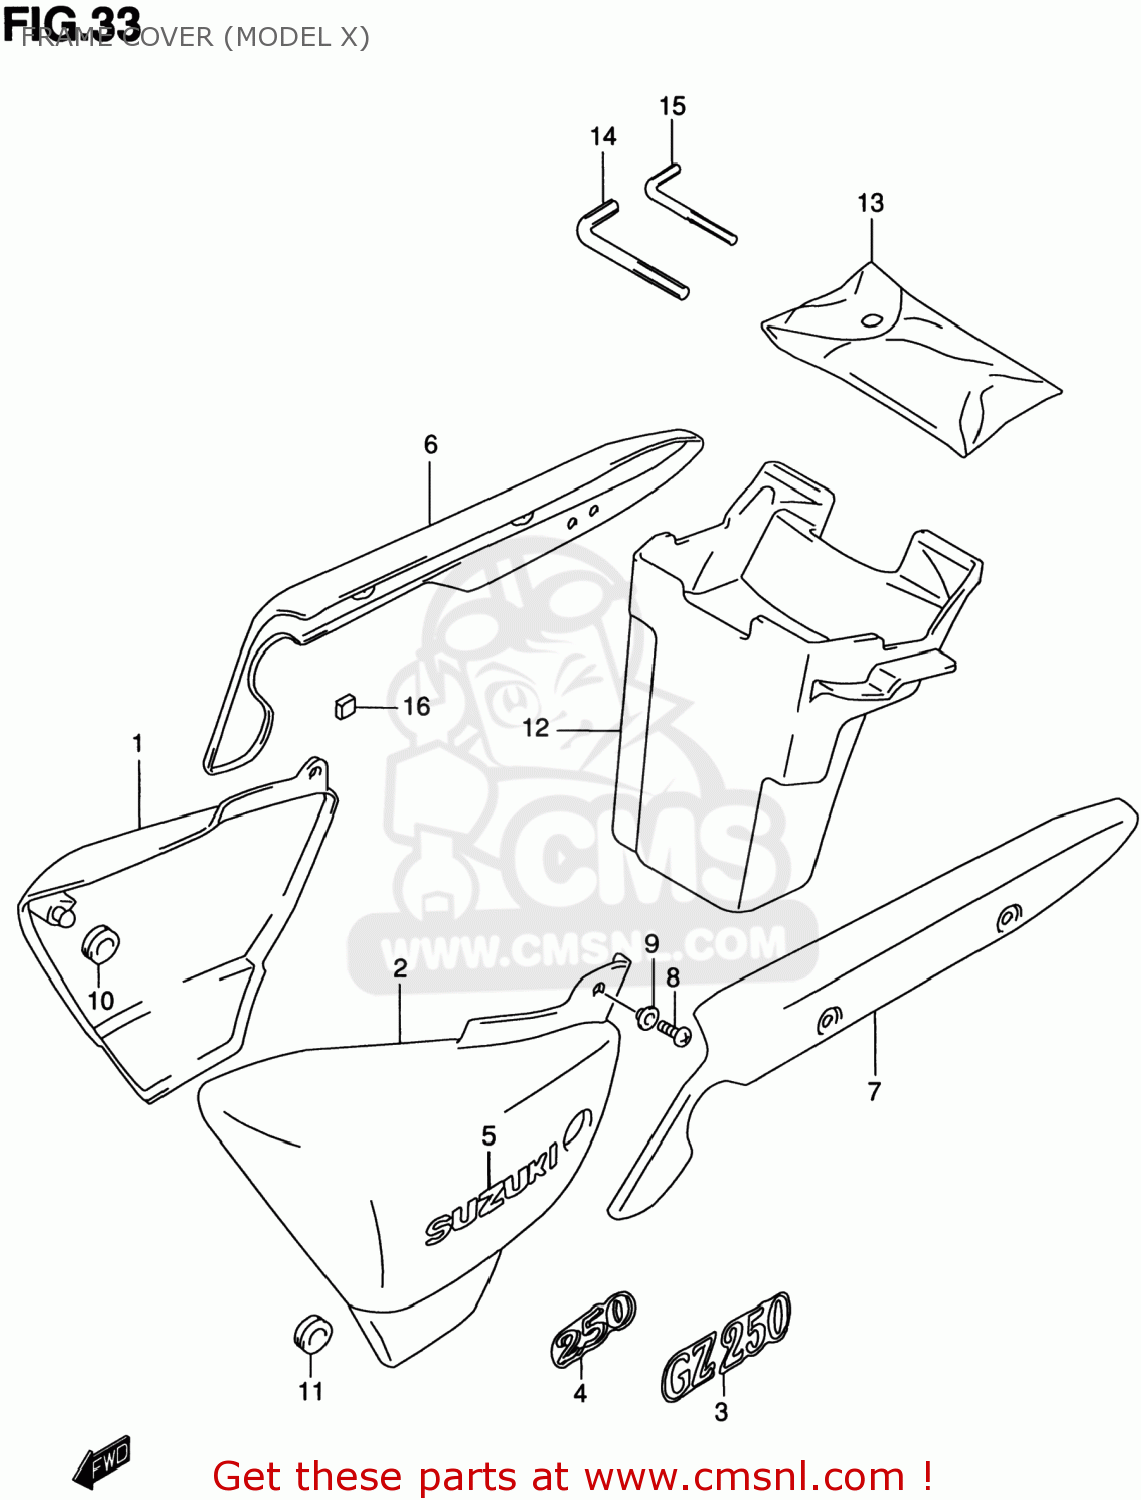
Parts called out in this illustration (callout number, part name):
1	COVER,FRAME,R(GREEN)
2	COVER,FRAME,L(GREEN)
3	EMBLEM,FRAME COVER
4	EMBLEM,250
5	EMBLEM,FRAME COVER
6	COVER,FRAME RR,R
7	COVER,FRAME RR,L
8	SCREW 6X12
9	WASHER
10	CUSHION
11	CUSHION
12	BODY,LUGGAGE BOX
13	TOOL ASSY
14	SPANNER,HEXAGON(6)
15	SPANNER,HEXAGON(4)
16	CUSHION
